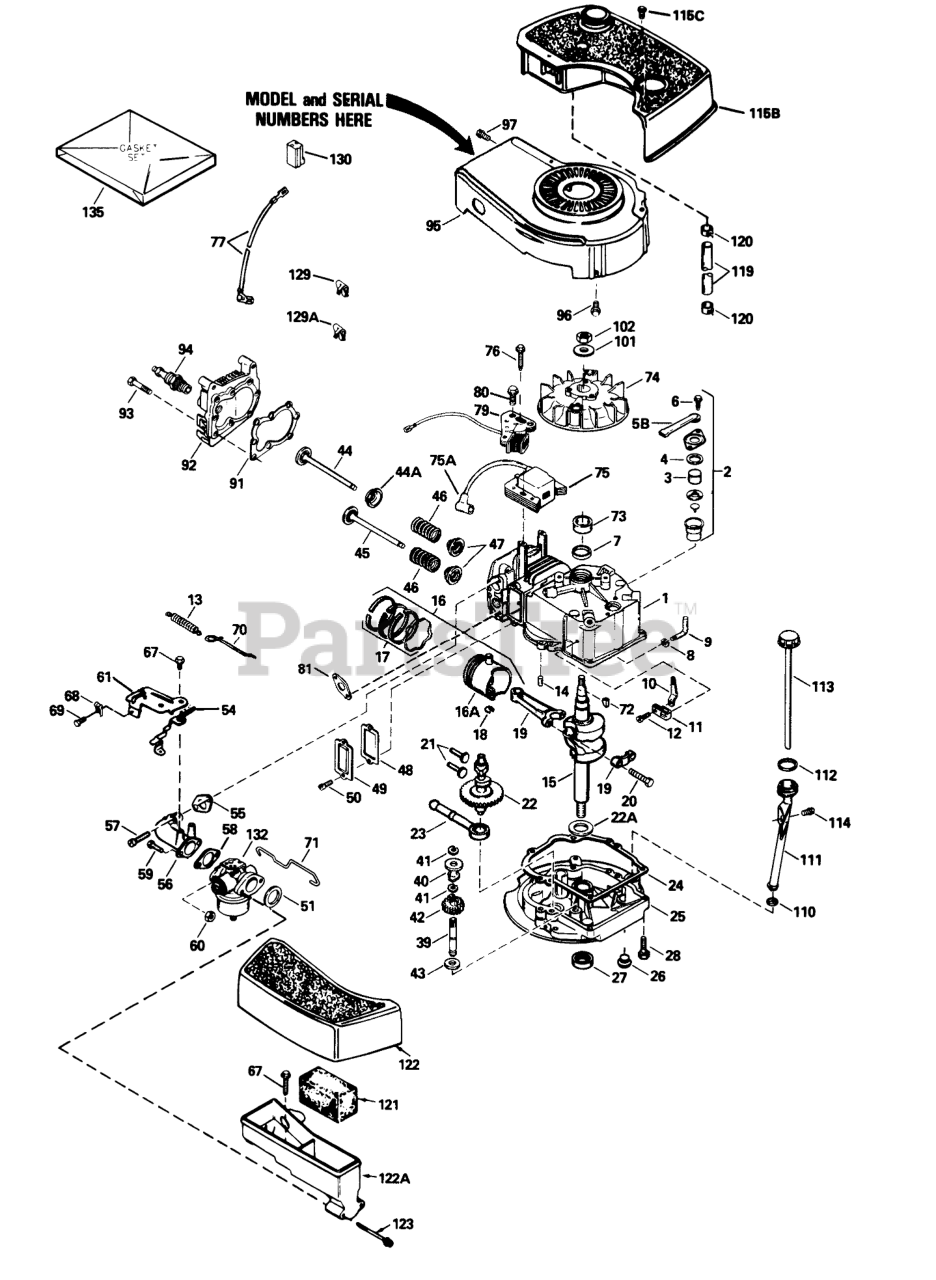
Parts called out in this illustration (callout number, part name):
1	Cylinder Assy. (Incl. Ref. #6 & 14)
2	Breather Assy. (Incl. Ref. #3-6 & 129)
3	Element-Breather
4	Gasket-Breather
5B	Tube, Breaker
6	Screw (10-24 x 9/16)
7	Seal-Oil
8	Washer-Flat
9	Rod, Governor (Incl. Ref. #8)
10	Governor Lever
11	Clamp-Lever, Governor
12	Screw
13	Spring Governor
14	Pin-Dowel
15	Crankshaft
16	Piston, Pin & Ring Assy. (STD.) (Incl. Ref . #16A, 17 & 18)
16	Piston, Pin & Ring Assy. (.010 oversize) (Incl. Ref. #16A, 17 & 18)
16	Piston, Pin & Ring Assy. (.020 oversize) (Incl. Ref. #16A, 17 & 18)
16A	Piston & Pin Assy. (Std.) (Incl. Ref. #18)
16A	Piston & Pin Assy. (.010 oversize) (Incl. Ref. #18)
16A	Piston & Pin Assy. (.020 oversize) (Incl. Ref. #18)
17	Ring Set-Piston (Std.)
17	Ring Set, Piston(.0100versize)
17	Ring Set (.020" OS)
18	Ring-Retaining, Piston Pin
19	Rod Assy., Connecting (Incl. Ref. #20)
20	Bolt-Rod, Connecting
21	Lifter-Valve
22	Camshaft(Mech.Comp. Release)
22A	Washer-Thrust
23	Oil Pump ASM
24	Gasket
25	Flange, Mounting (Incl. Ref. #26, 27 & 39)
26	Plug Oil Drain
27	Seal-Oil
28	Screw (1/4-20 x 1-1/4)
39	Shaft-Governor
40	Spool-Governor
41	Ring-Retaining
42	Gear Assy., Governor (Incl. Ref. #43)
43	Washer
44	Valve, Intake (Std.) (Incl. Ref. #47)
44	Valve, Intake (1/32" oversize) (Incl. Ref. #47)
44A	Seal Assy., Intake
45	Valve, Exhaust (Std.) (Incl. Ref. #47)
45	Valve, Exhaust (1/32 " oversize) (Incl. Ref. #47)
46	Spring-Valve
47	Cap-Valve, Spring
48	Gasket-Cover, Valve
49	Cover-Valve
51	Gasket-Air Cleaner
54	Lever Control
55	Gasket-Intake Pipe
56	Pipe, Intake (Incl. Ref. #55)
57	Screw (1/4-20 x 1)
58	Gasket-Carburetor
59	Screw (1/4-28 x 7/8)
60	Nut and Lock Washer (1/4-28)
61	Bracket Assy., Control (Incl. Ref. #54 & 67)
67	Screw, Hex Washer Hd Shoulder Self-Tap
68	Conduit
69	Screw (10-32 x 3/8)
70	Link Governor Spring
71	Link-Throttle
72	Key-Flywheel
74	Flywheel
75	Solid State
75A	Cover-Spark Plug
76	Screw
77	Wire-Ground
79	Coil, Alternator
80	Screw (8-32x27/64)
81	Gasket, Exhaust
91	Gasket-Cylinder Head
92	Head-Cylinder
93	Screw (5/16-18x1-1/2)
94	Spark Plug-Resistor (R J19 L M)
95	Housing-Blower
96	Screw (1/4-20x19/32)
97	Screw (10-24 x 9/16)
101	Washer-Belleville
102	Nut-Flywheel
111	Tube, Oil Fill
113	Dipstick, Oil
114	Screw (10-32 x 1/2)
115B	Tank Assy. (Incl. Ref. #118 & 120)
115C	Screw (10-32 x 35/64)
119	Line-Fuel
120	Clamp-Line, Fuel
121	Filer, Air
122	Cove, Air Cleaner
122A	Body Air Cleaner
123	Screw Fil Hd.
129	Clip-Wire
129A	Clip, Breather
130	Connector-Body
132	Carburetor (Incl. Ref . #58)
135	Gasket Set (Incl. items marked )
